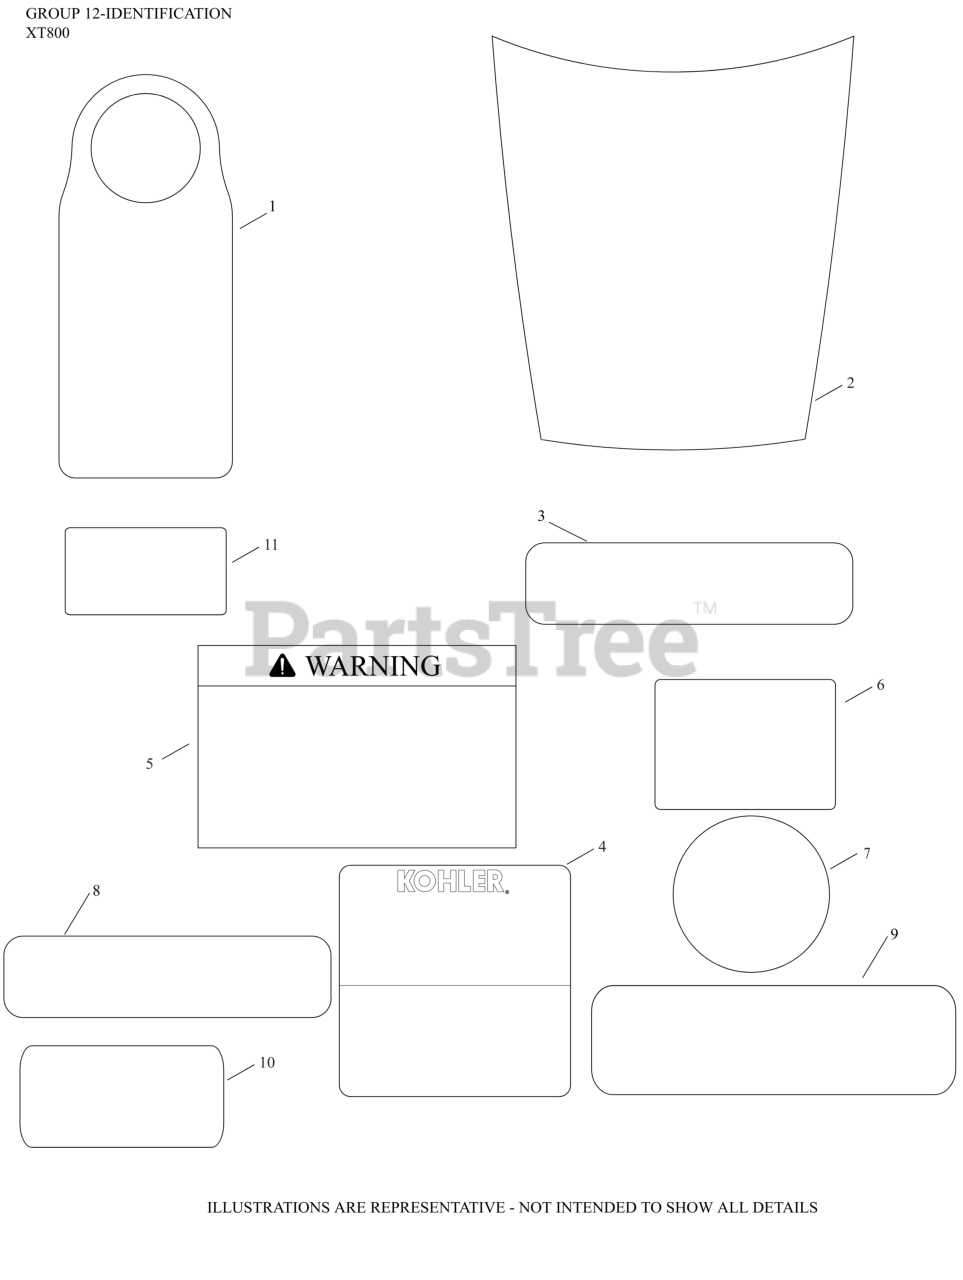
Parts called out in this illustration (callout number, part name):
2	DECAL, NAME XT8 - UTILITY STYLING
4	NAMEPLATE, SERVICE
5	DECAL, WARNING
10	DECAL, ON/OFF ROCKER SWITCH
11	DECAL, RUN/CHOKE
